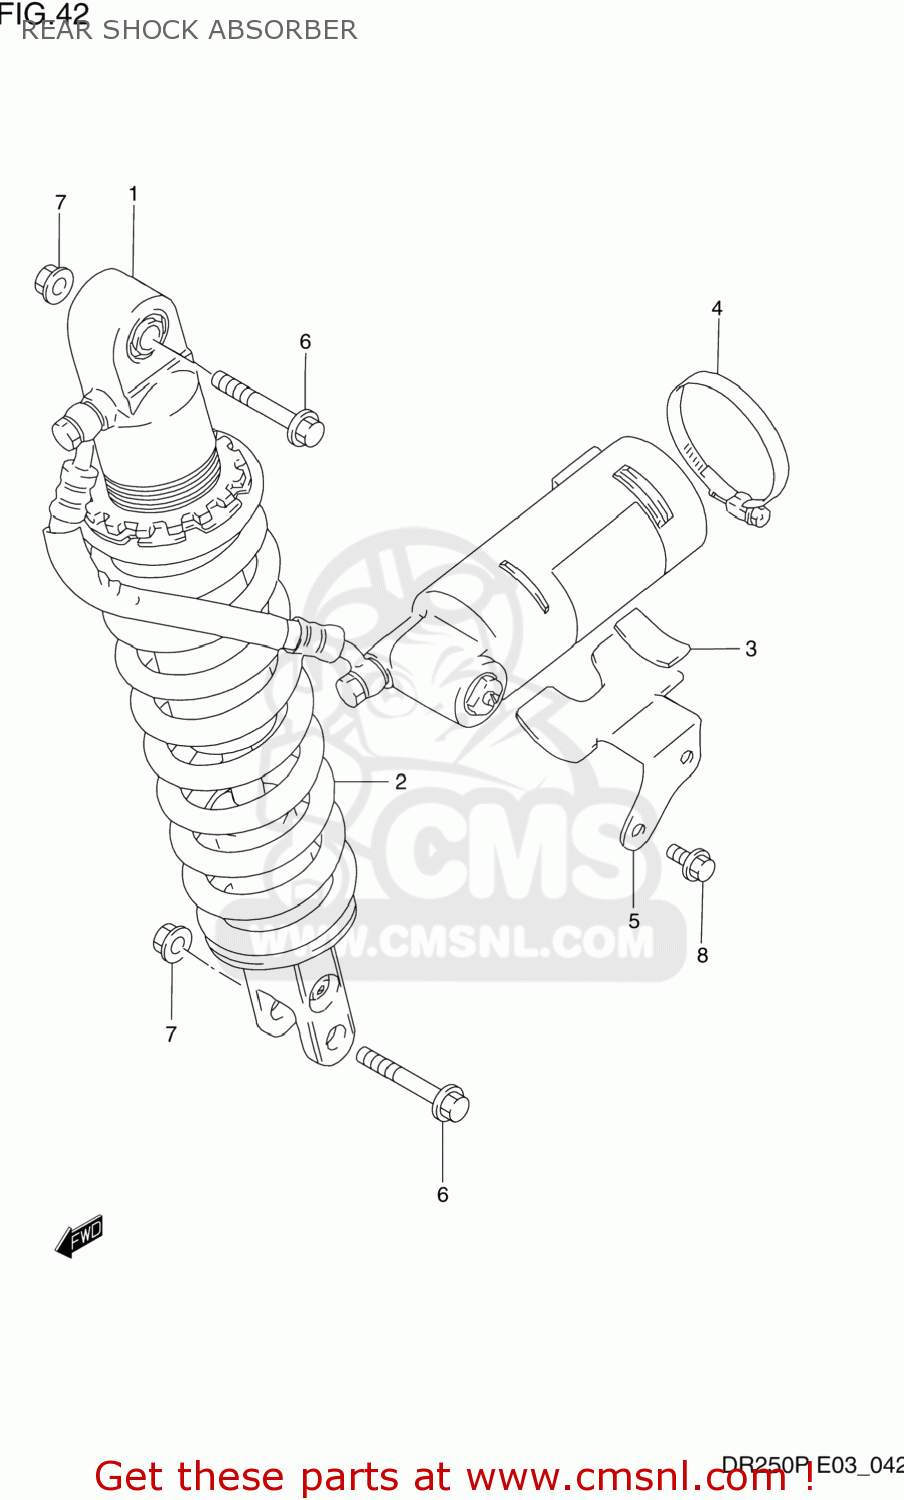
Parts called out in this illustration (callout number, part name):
1	ABSORBER ASSEMBLY,REAR SHOCK
2	SPRING
3	CUSHION,REAR SHOCK ABSORBER
4	CLAMP
5	BRACKET,RESERVOIR TANK
6	BOLT,REAR SHOCK ABSORBER
7	NUT
8	BOLT
